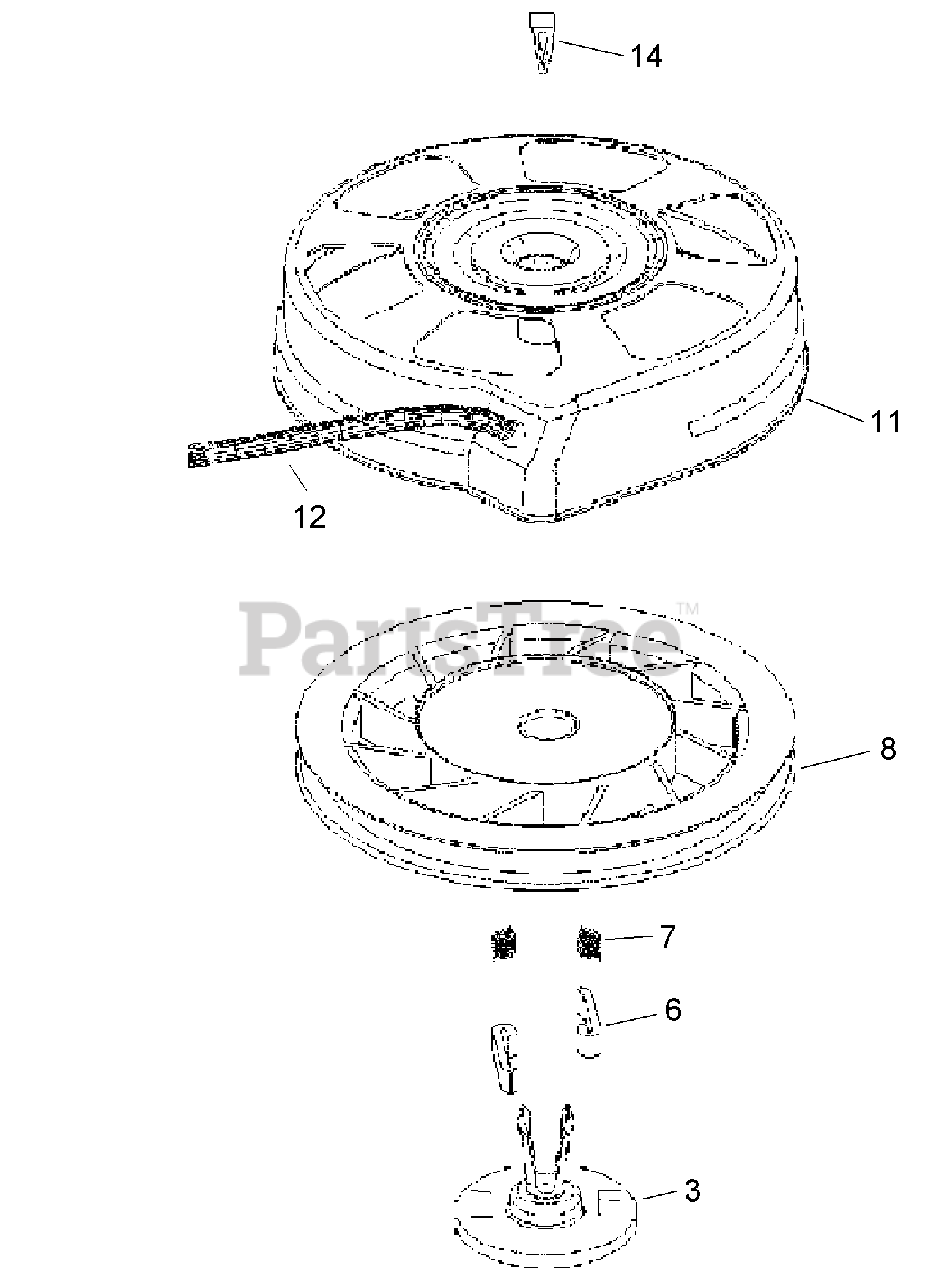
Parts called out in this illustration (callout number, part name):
3	Retainer
6	Dog-Starter
7	Spring-Dog
8	Pulley and Rewind Spring ASM
11	Starter Housing ASM
12	Rope-Starter (98in X 9/64in diameter)
14	Clip-Spring
